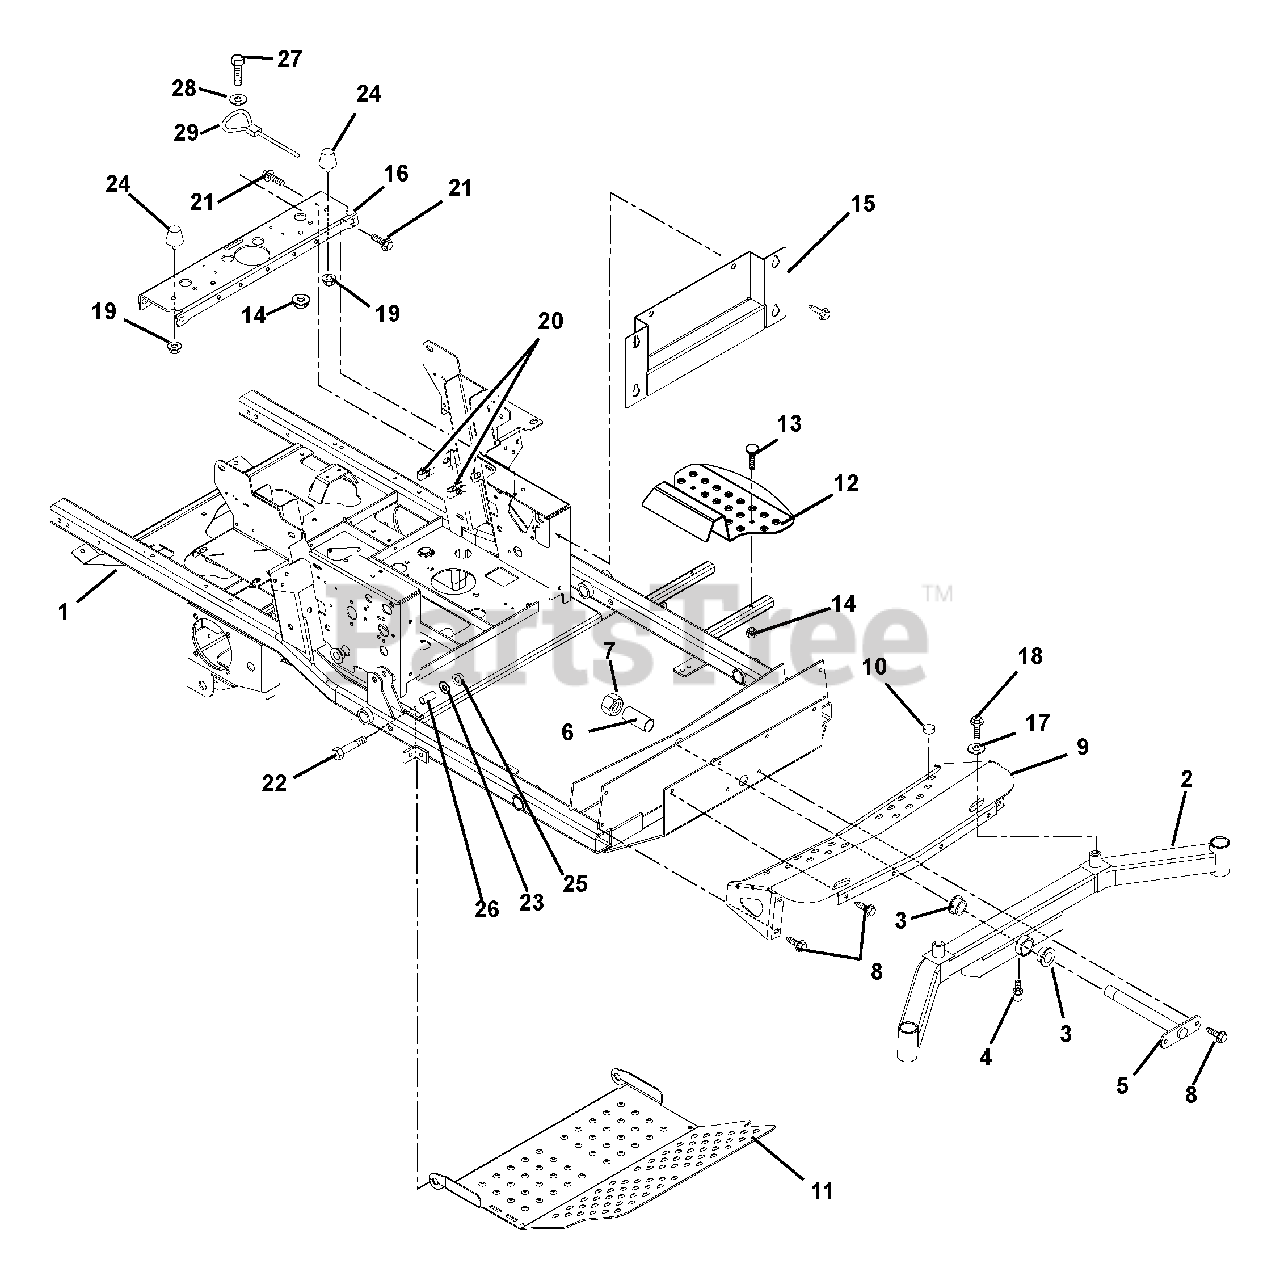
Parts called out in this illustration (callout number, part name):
1	Weldment, Frame
2	Weldment, Axle
3	Bushing, Flange 1.02 x 1.385 x .75 x 1.75
4	Fitting, Lube 45 Degree GM411031
5	Pin, Axle
7	Nut, Locking Nylon 1.00-14
8	Screw, Tapping .38-16 x .75
9	Weldment, Axle Cover
10	Button, Rubber
11	Panel, Inspection
12	Step, Ingress
13	Bolt, Round Head Square Neck .31-18 x 1.75 Grade 5
14	Nut, Locking Top Flange .31-18
15	Plate, Kick
16	Channel, Cross
17	Washer, Flat Steel .640 x 1.81 x .25
18	Bolt, Hex .50-20 x 1.00 Grade 5
19	Nut, Locking Flange .312-18
20	Nut, Retainer .375-16 x .37
21	Bolt, Serrated Hex Flange Washer Head .38-16 x 1.00
22	Bolt, Hex .50-13 x 3.25 Grade 5
23	Washer, Flat Steel .563 x 1.38 x .109
25	Nut-Locking-Top-Flange .50-13
26	Bushing, Flange .515 x .75 x .275 x 1.12
27	Bolt, Hex .31-18 x .75 Grade 5
28	Washer, Flat Steel .344 x 1.25 x .135
29	Cable, Seat Prop.
